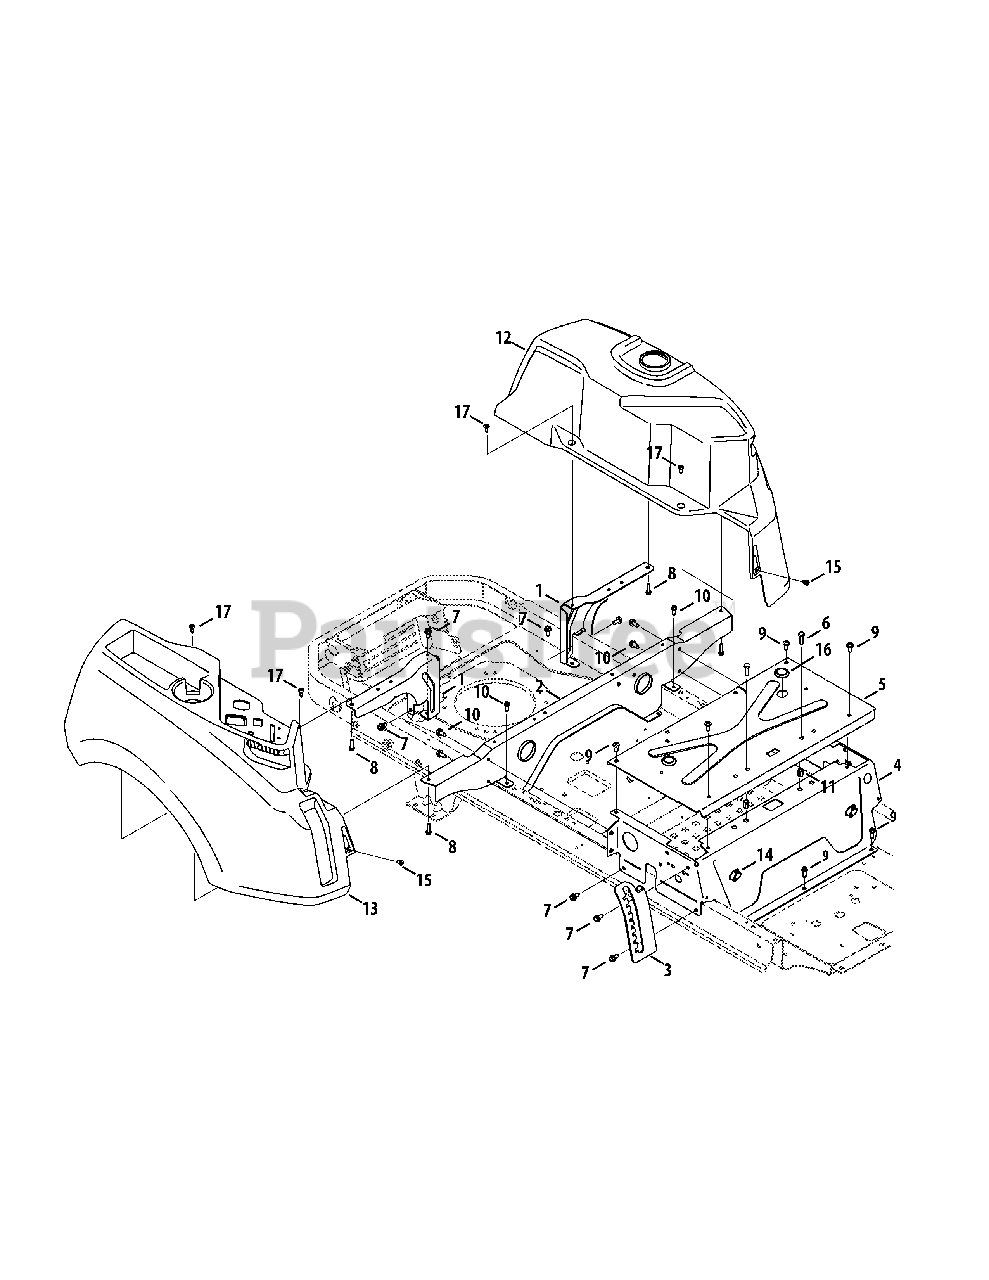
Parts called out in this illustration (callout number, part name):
1	Rear Tank Bracket
2	Rear Seatbox Brace
3	Height Index Bracket
4	Seat Frame
5	Seatbox Plate
6	Hex Cap Screw, 5/16-18 x 1.00
7	Hex Washer Screw, 5/16-18 x .750
8	Hex Washer Screw, 5/16-14 x 1.00
9	Self Tapping Screw, 5/16-18 x .750
10	Hex Washer Screw, 5/16-18 x .50
11	Nut, 5/16-18
12	LH Console
13	RH Console
14	Plastic Plug
15	Shoulder Screw, 1/4-20
16	Button Plug
17	Shoulder Screw, .368 x .115, M6-1
